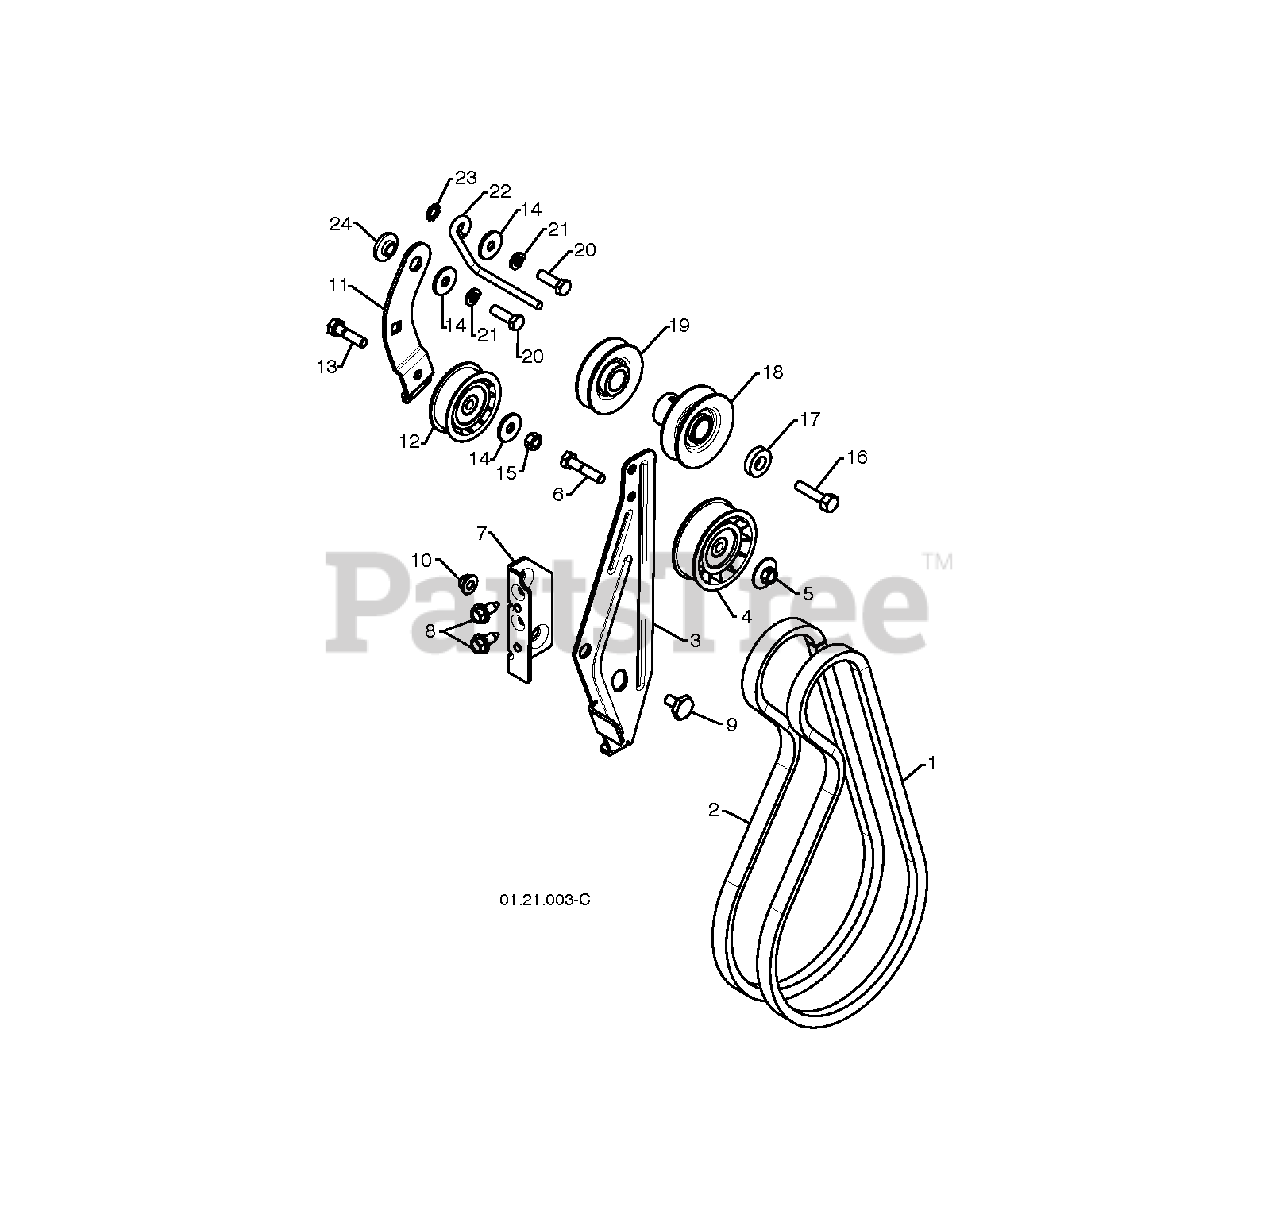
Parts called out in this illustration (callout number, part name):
1	BELT.V.IMPELLER
2	V-BELT.TRACTION
3	RP ARM.IDLER.BRAKE
4	PULLEY.W/SPACER.2.75
5	NUT.FLANGE.HEX.5/16X18.BLACK
6	HEX BOLT
7	RP BRACKET.IDLER
8	BOLT.HEX.HD.WASHER.5/16-18X.75
9	BOLT.SHOULDER.1/2X12
10	NUT, LOCK 5/16-18
11	ARM, IDLER
12	PULLEY.W/SPACER.2.25
13	BOLT.5/16-18X1-1/4 FULL.THREAD
15	NUT.71038.31-18.HEX.NYLOCK
16	SCREW, HEX HD 3/8-24 X 1-3/8
17	WASHER, FLAT 3/8
18	PULLEY.IMPELER.
19	PULLEY.ENG.TRACTION
23	WASHER EXT TOOTH LOCK 5/16
24	BUSHING, IDLER PIVOT
